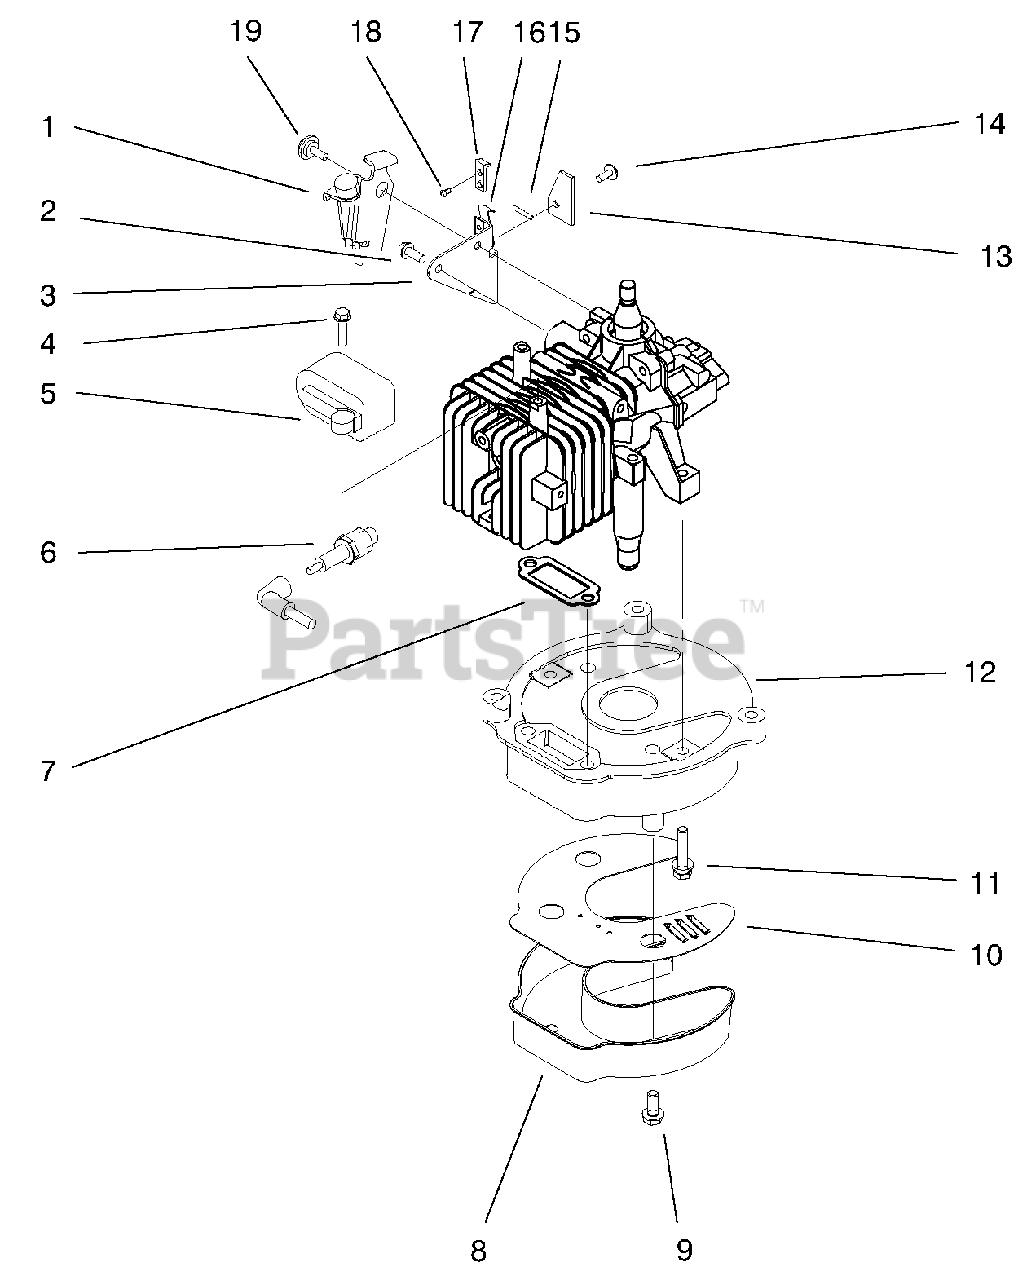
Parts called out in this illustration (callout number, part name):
1	Brake Plate ASM
2	Screw
3	Plate-Mount Brake
4	Screw-HWH
5	Ignition ASM
6	Plug-Spark
7	Gasket-Exhaust
8	Cover-Muffler
12	Plate-Muffler
13	Stop-Ground Strap
14	Screw-Thread Forming
15	Brake Switch Lead Wire
16	Strap-Ground
17	Strap-Insulation
18	Rivet-Self Expanding
19	Screw-Shoulder
